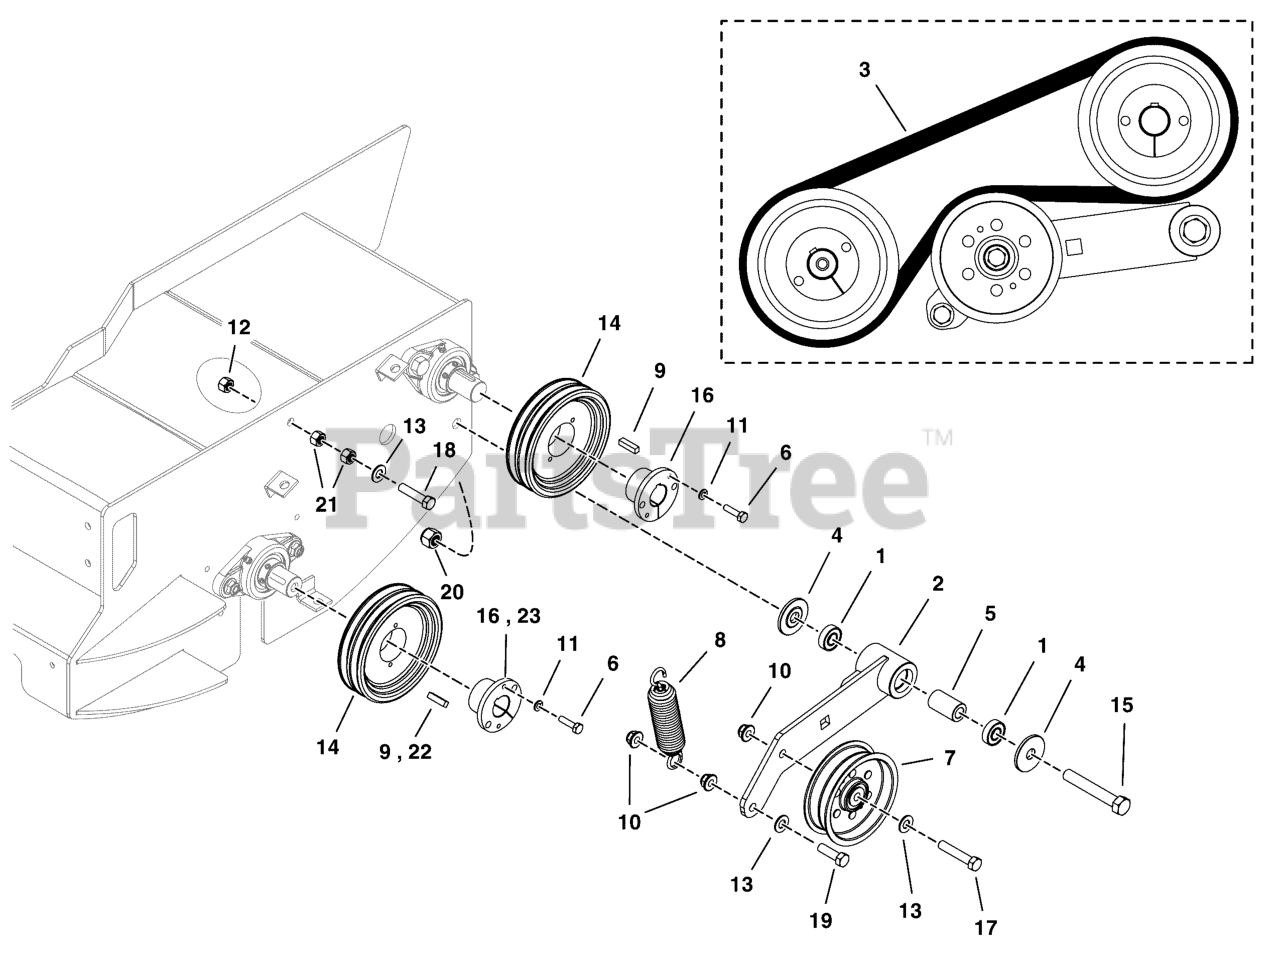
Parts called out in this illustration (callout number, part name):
1	BEARING, BALL, AXLE
2	WELD, IDLER ARM, 8.50, BB - RED
3	BELT, DOUBLE A BANDED, 43"EL, RAW EDGE
4	SPACER, IDLER ARM, 1/2"
5	SPACER, .52 X .84 X 1.53, PM
6	BOLT, 1/4-20 X 1" GD5 CZ
7	PULLEY, IDLER, DOUBLE FLGED, 4IN
8	SPRING-EXT, 1.25 ODX5.70LGX.142WR, BLK
9	KEY, 1/4" SQR. X 1-1/4, RD ENDS
10	NUT, 3/8-16 HEX NYLOCK FLANGE
11	WASHER, 1/4 LOCK
12	NUT, 3/8-16 HEX SIDE LOCK
13	WASHER, 3/8 SAE
14	PULLEY, GEARBOX INPUT
15	BOLT, 1/2-13 X 3-1/2, HEX HD, GD5, CZ (SV)
16	BUSHING, TAPERED HUB
17	BOLT, 3/8-16 X 2, GD5, CZ
18	BOLT, 3/8-16 X 1-1/2" GD5 CZ
19	BOLT, 3/8-16 X 1-1/4" GD5 CZ
20	NUT, 1/2-13 HEX NYLON LOCK
21	NUT, 3/8-16 HEX
22	KEY, 8MM X 8MM X 25MM
23	BUSHING, TAPER LOCK, 25MM
